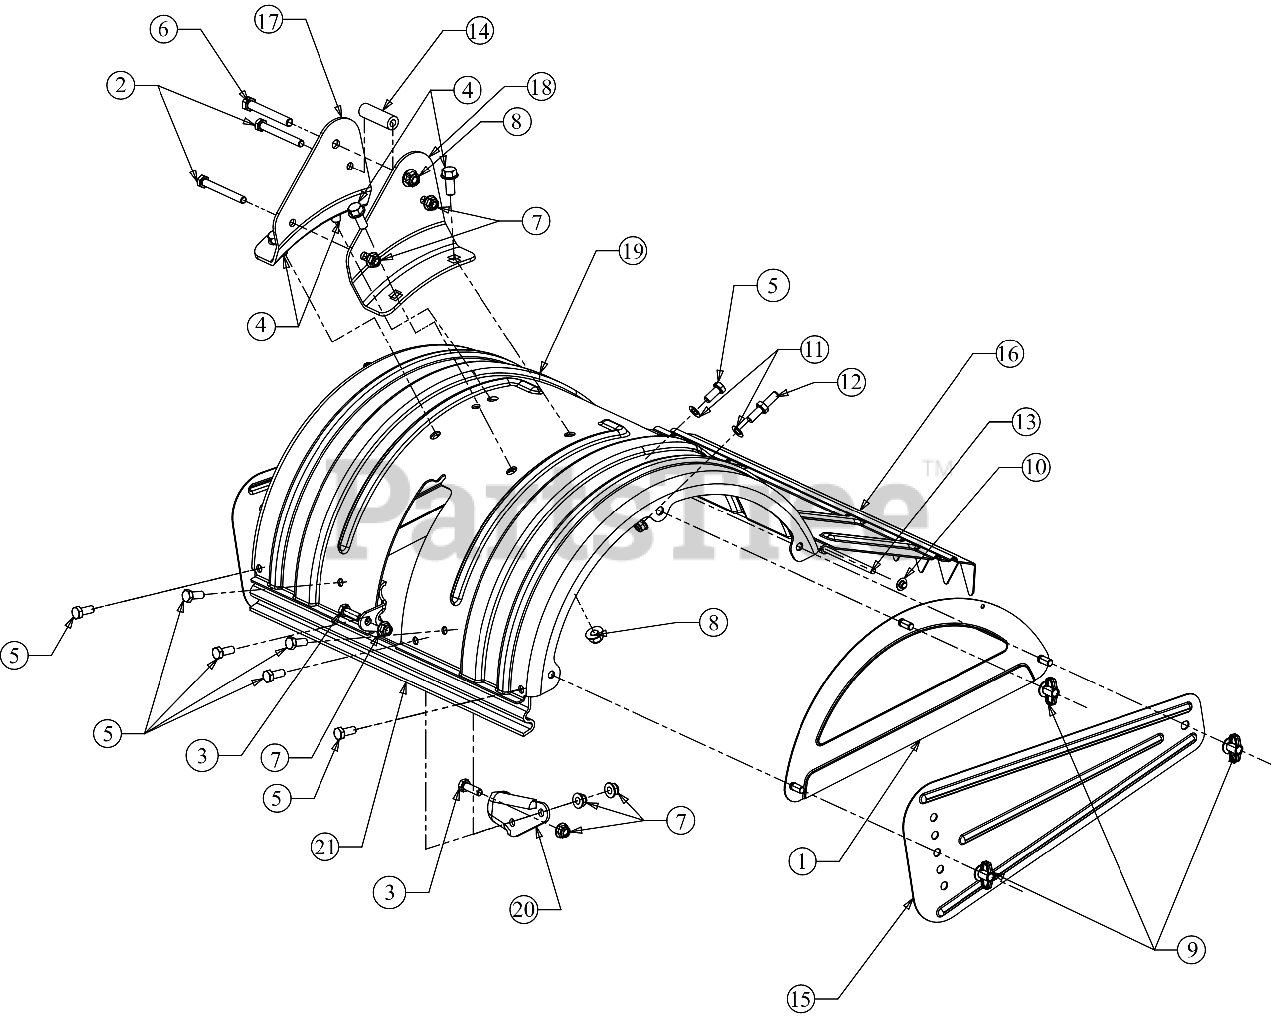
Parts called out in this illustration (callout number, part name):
2	HEX SCREW 5/16-18 X 2.75
3	SCREW 5/16-18 X 1.0 GR5
4	SCREW 3/8-16 X .875 GR5
5	SCREW 5/16-18 x .75 GR5
6	SCREW 3/8-16 X 2.75 GR5
7	FLANGE LOCK NUT 5/16-18
9	WING NUT 5/16-18
10	PUSH NUT
11	FLAT WASHER .344 ID X .62 OD X .033
12	SHOULDER SCREW
13	TILLER FLAP ROD
14	SPACER
20	TINE SHIELD BRACKET
21	SHOULDER SPACER BRACKET
